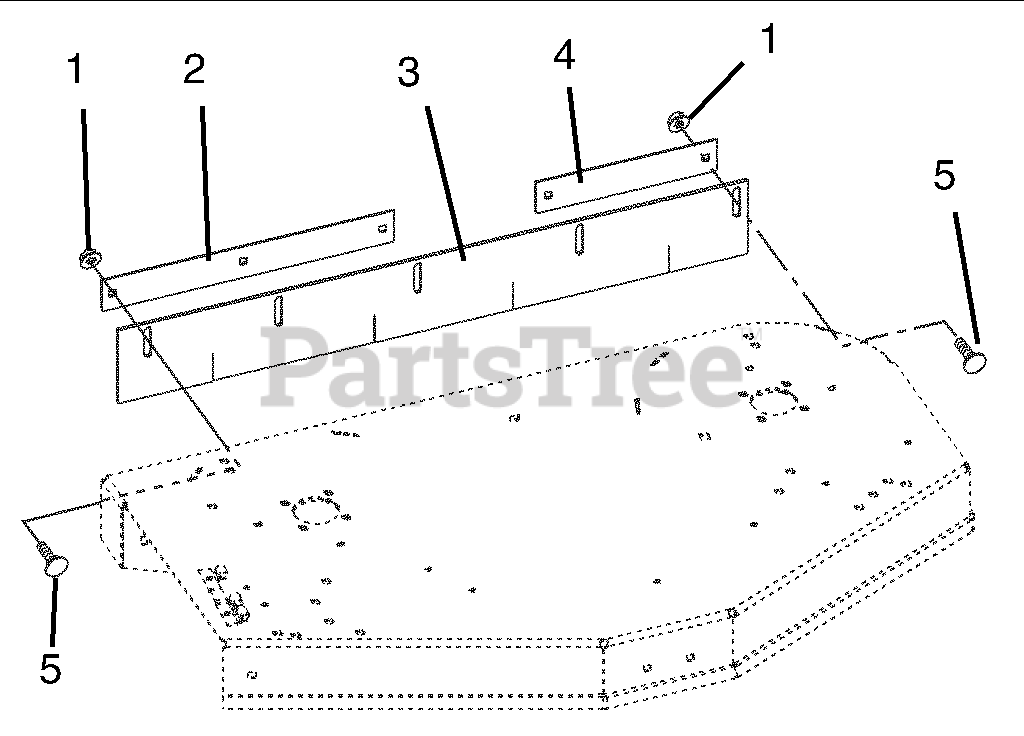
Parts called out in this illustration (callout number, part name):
1	@NUT-LK-NYL-FLG .38-16 YWZC
2	BAR, RETAINING STRIPER-40"
3	STRIPER, RUBBER-40"
4	BAR, LH RETAINER STRIPER
5	@BLT-RDHDSQNK .38-16X1.00 G5YZ
